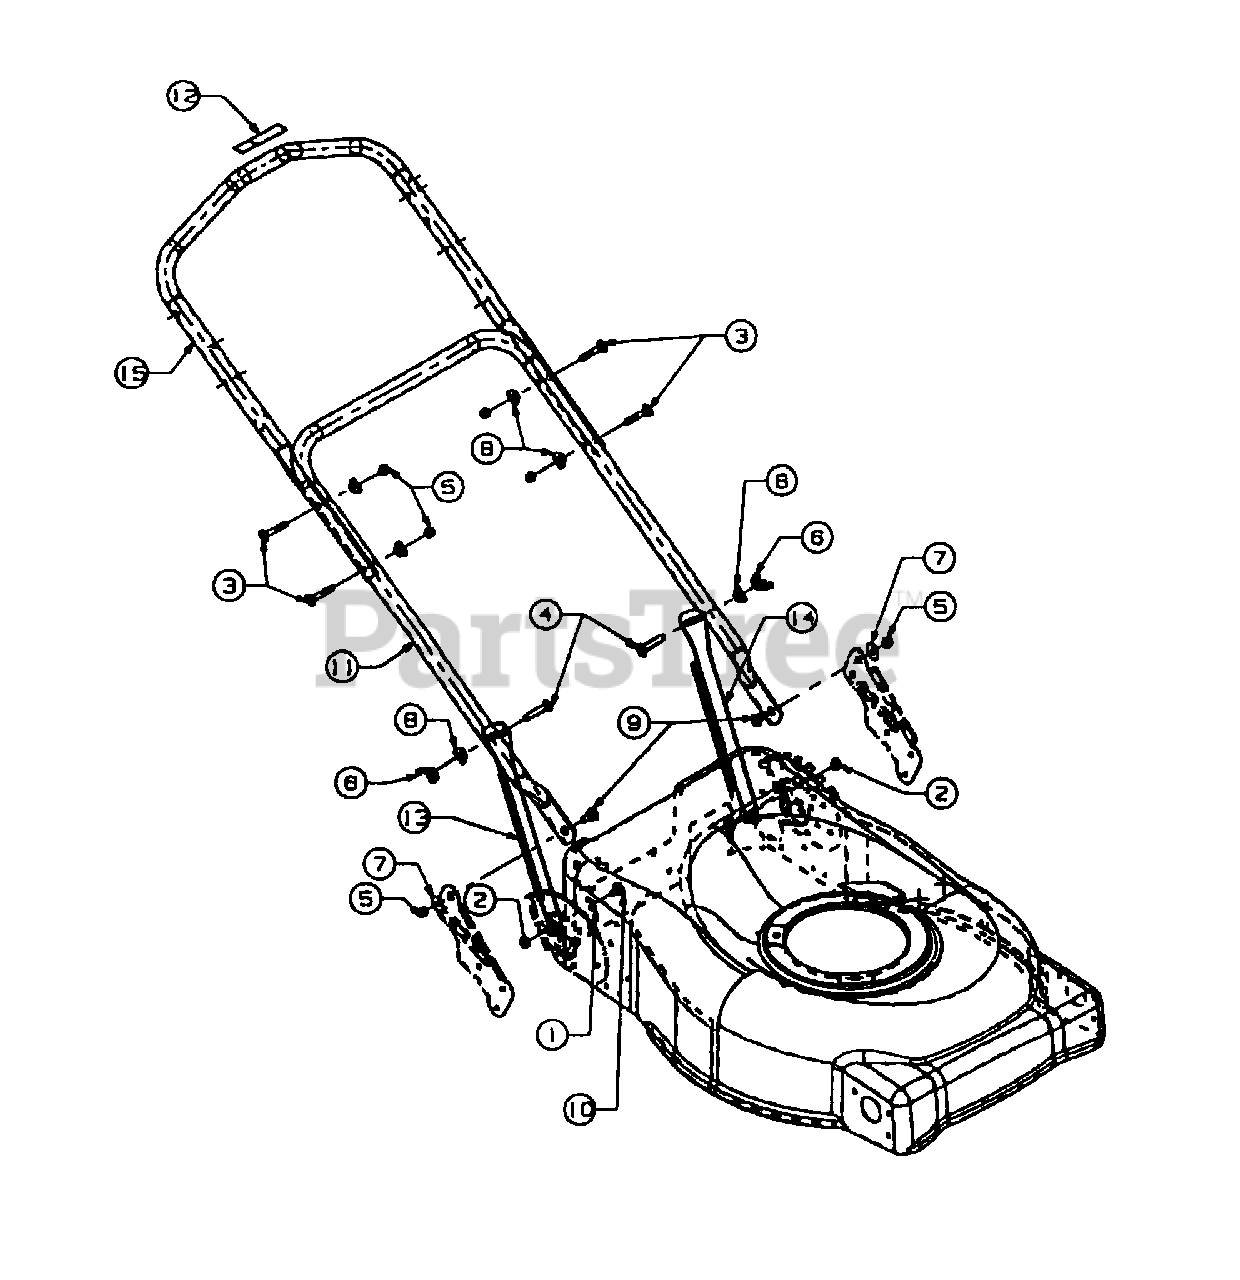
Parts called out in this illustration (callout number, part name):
1	WASH: THRUST
2	NUT:LOCK:5/16-18 X 1.75
3	BOLT:CARR:5/16-18 X 1.75
4	BOLT:CARR:5/16-18 X 1.75
5	NUT: HX:5/16-18: LOCK
7	WASH:BELL: .325 X .930 X .045
8	WASHER,SADDLE:320 ID X .93 OD
9	SCR:SHOULDER: .435 X .350: 5/16-18
10	BOLT:SHLD: .437 X 1.82 LG.
11	HANDLE:LOWER
12	DECAL: CAUTION
13	STRUT:HNDL:3 POSITION:RH
14	STRUT:HNDL:3 POSITION:LH
15	HANDLE:UPPER
